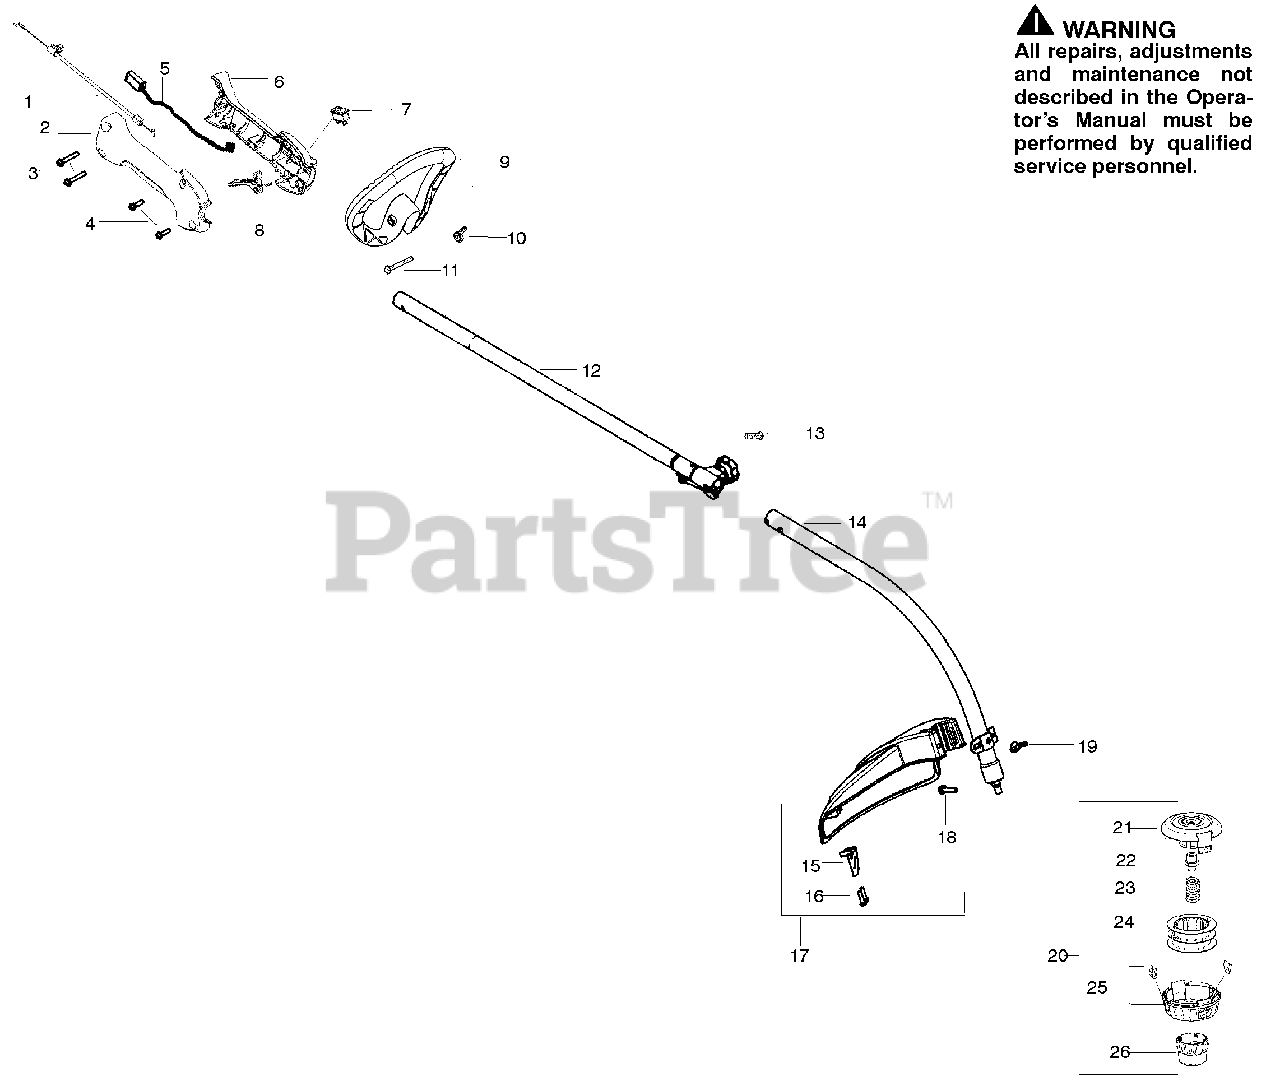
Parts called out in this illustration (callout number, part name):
1	Assy-Throttle Cable
2	Hsg.-Throttle (RH)
5	Assy.-Wire
6	Hsg. Throttle (LH)
7	Kit-Switch
8	Trigger-Throttle
9	Assy-Handle-Assist
10	Wingnut
12	Kit-Upper Shaft
14	Kit-Lower Shaft
15	Limiter-Line
17	Kit-Shield Assy.
19	Wingnut
20	Accy-TNG7
24	Assy-Wound Spool
25	Kit-Cover and Eyelet
